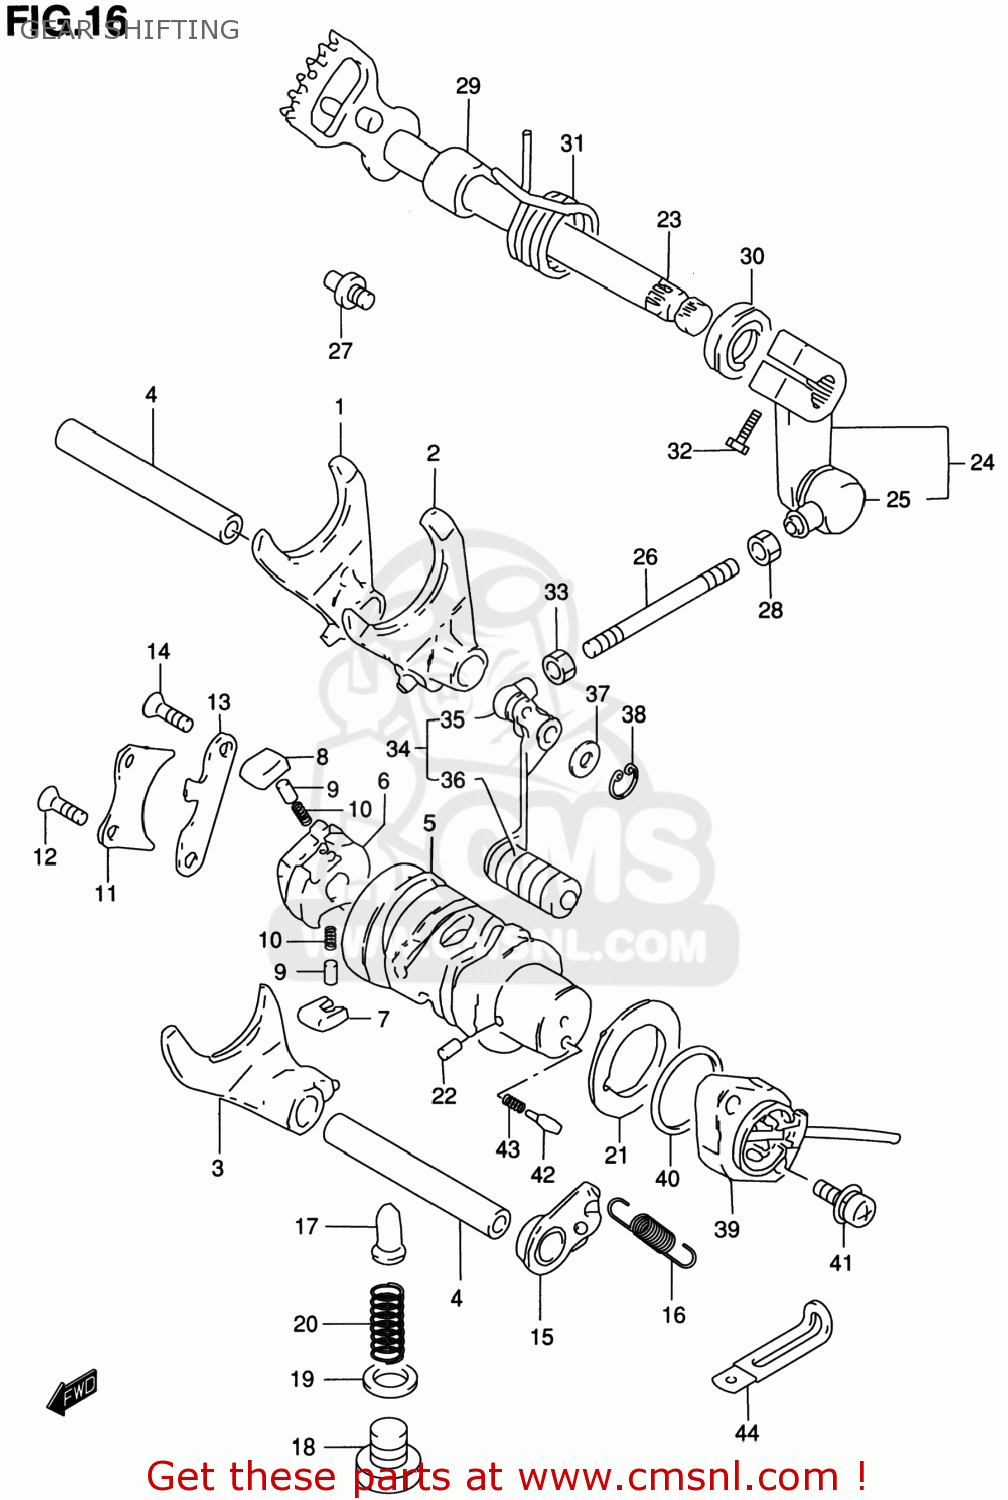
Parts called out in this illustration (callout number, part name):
1	FORK,GEAR SHIFT NO.1
2	FORK,GEAR SHIFT NO.2
3	FORK,GEAR SHIFT NO.3
4	SHAFT,GEAR SHIFT FORK
5	CAM,GEAR SHIFT
6	GEAR,GEAR SHIFT CAM DRIVEN
7	PAWL,GEAR SHIFT NO.1
8	PAWL,GEAR SHIFT NO.2
9	PIN(5X8)
10	SPRING
11	LIFTER,GEAR SHIFT POLE
12	SCREW
13	GUIDE,GEAR SHIFT CAM
14	SCREW
15	STOPPER,GEAR SHIFT CAM
16	SPRING
17	STOPPER,GEAR SHIFT CAM NO.2
18	PLUG (14X12)
19	GASKET(13.8X18.8X4.8) (NAS)
20	SPRING
21	PLATE,GEAR SHIFT CAM STOPPER
22	PIN
23	SHAFT,GEAR SHIFT
24	ARM,GEAR SHIFT LINK
25	COVER,DUST
26	ROD,GEAR SHIFT LINK
27	STOPPER,GEAR SHIFT CAM
28	NUT
29	SPACER(12X20X15.3)
30	OIL SEAL
31	SPRING
32	BOLT
33	NUT
34	LEVER ASSY,GEAR SHIFT
35	COVER,DUST
36	RUBBER,GEAR SHIFT PEDAL
37	WASHER(12.5X20X1)
38	CIRCLIP,12 MM
39	BASE ASSY,NEUTRAL SW TERMINAL
40	O-RING (D:2.4 ID:26.2)
41	SCREW
42	PIN(5X15.5)
43	SPRING
44	CLAMP(L:65)
